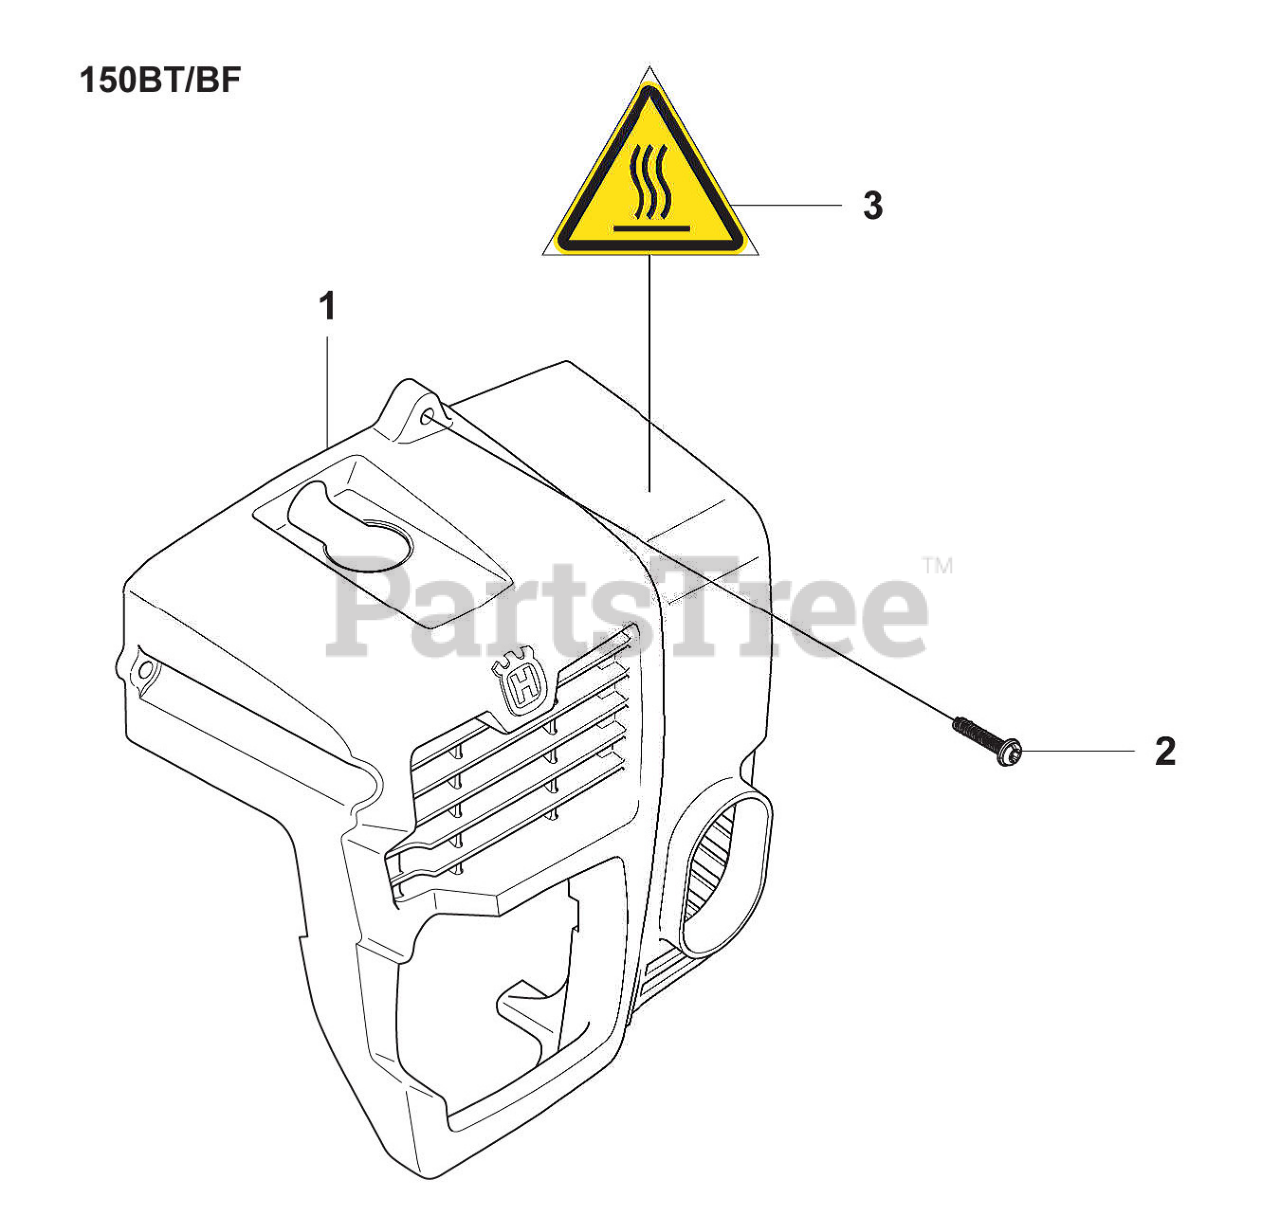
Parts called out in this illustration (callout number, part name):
1	Cylinder Cover
2	Screw
3	RP_LABEL, HOTMARK
